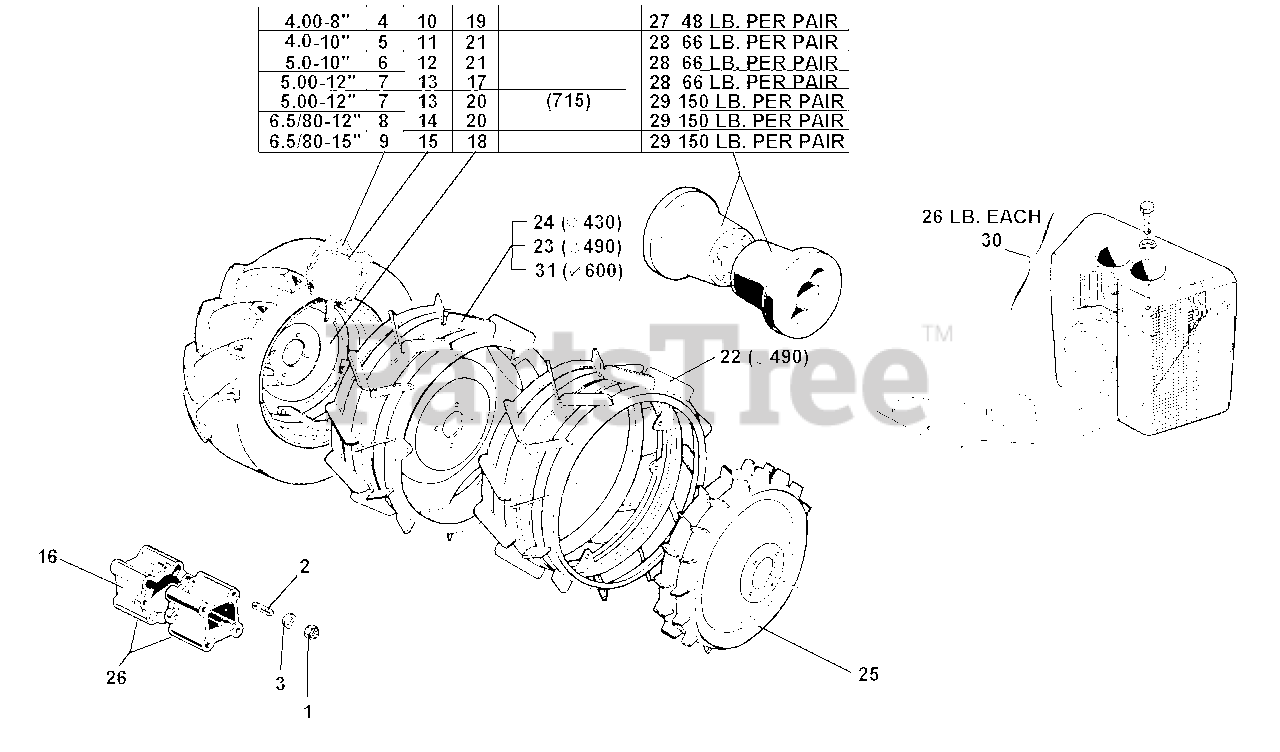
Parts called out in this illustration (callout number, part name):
2	STUD M10 X 40 X 22 X 14
3	WASHER, LOCK 10.5
4	TIRE TRACTOR 4.00 X 8
5	TIRE TRACTOR 4.0 - 10
6	TIRE 5.0 X 10
7	TIRE 5.00 - 12
8	TIRE 6.5/80 - 12
9	TIRE TRACTOR 6.5/80 X 15
10	TUBE 4.00 X 8
11	TUBE 4.0 - 10
12	TUBE 5.0 - 10
13	TUBE 5.00 - 12
14	TUBE 6.5/80 X 12
15	TUBE 6.5/80 X 15
16	WHEEL SPACER
17	RIM, 12 OFFSET COUPLING
18	RIM 5 J 15 INCH ADJ. TRACK
19	WHEEL, DISK, 2.50 - 8
20	RIM 5JA - 12 INCH. ADJ. TRACK
21	RIM 3.50 D 10 (INCH) C.VAR.COM.
22	RINGS, 19" CAGE WHEELS (PR)
23	WHEELS, STEEL CAGE, 19" (PR)
24	WHEELS, STEEL CAGE, 17" (PR)
25	NARROW NURSERY WHEELS (PR)
26	WHEEL SPACERS, 2.5" (PR)
27	WEIGHTS FOR 4.00 X 8, (48#)(PR)
28	WEIGHTS FOR 10"/12", (66#)(PR)
29	WEIGHTS,6 X 12/6.5 X 15,(150#)(PR)
30	WEIGHT FOR CUTTER BAR, (EA)
31	WHEELS, STEEL CAGE, 24" (PR)
